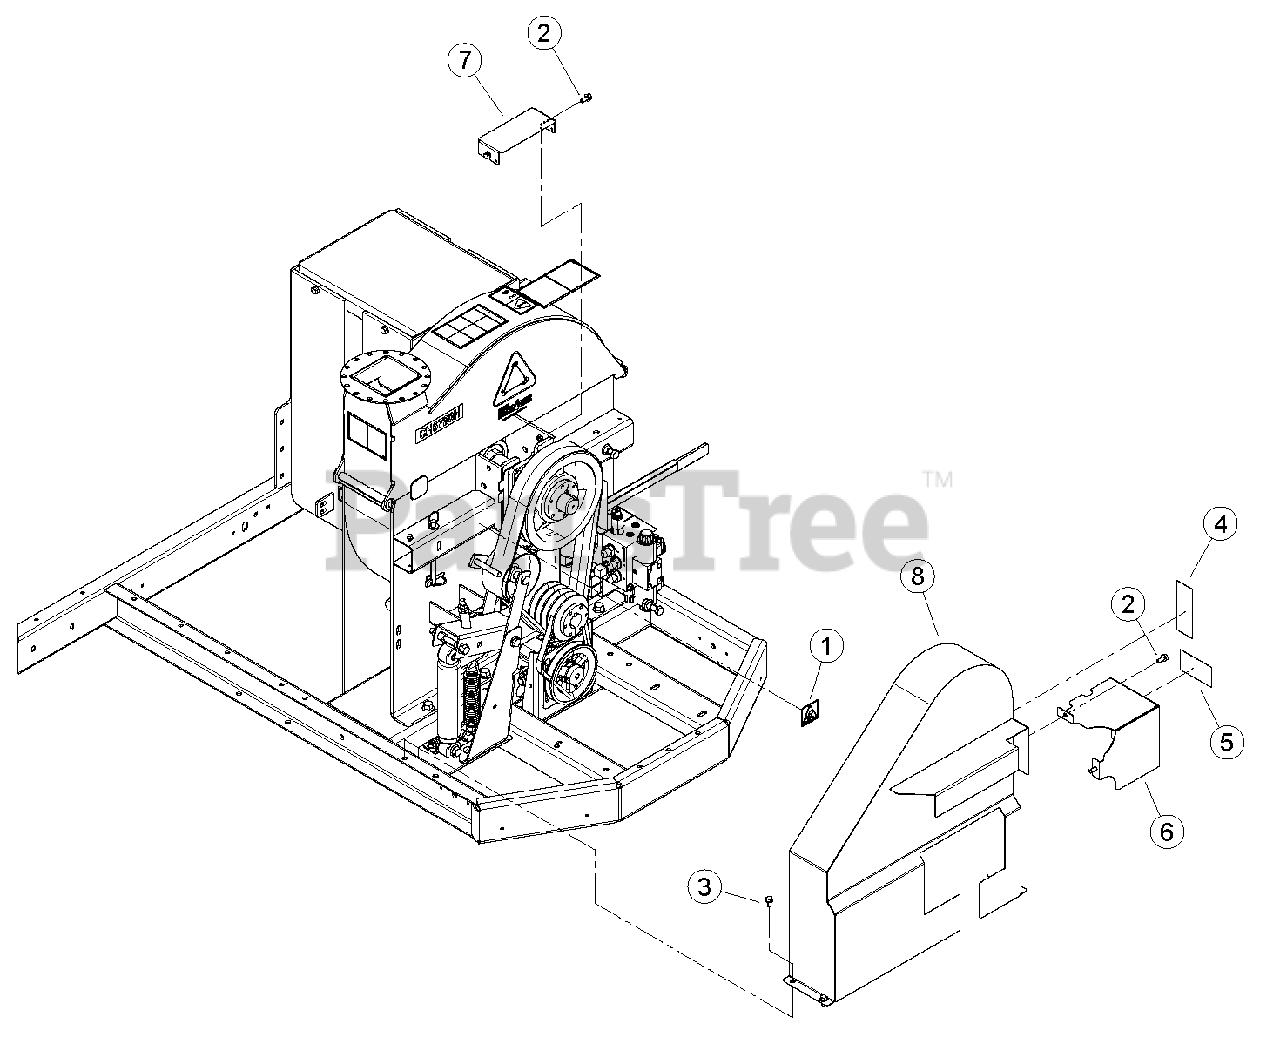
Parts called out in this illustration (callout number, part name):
1	DECAL, SHIELD DANGER ISO
2	BOLT, 5/16 X 3/4 FLANGE NC
3	BOLT, 5/16 X 5/8 FLANGE NC
4	DECAL, CHIPPER ENGAGEMENT
5	DECAL, FEED SPEED
6	COVER, FEED VALVE 6"
7	COVER, CHIPPER SHAFT
8	WELDMENT, BELT SHIELD
